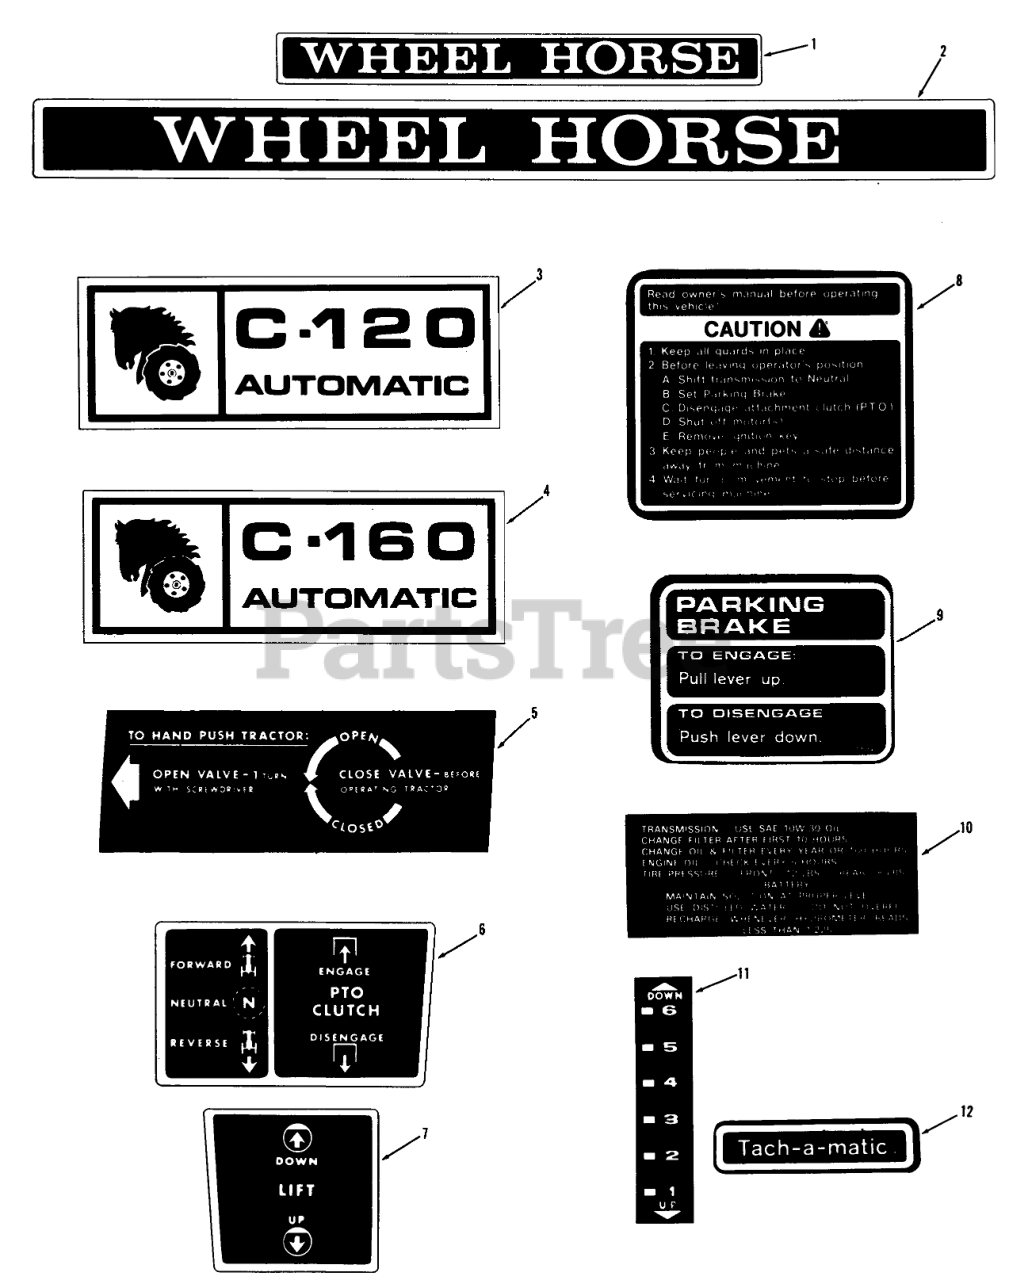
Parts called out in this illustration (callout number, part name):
1	DECAL-WHEEL HORSE
2	Decal
3	Decal
4	DECAL C 160
5	Lockwasher
6	DECAL PTO SPD. CONT
7	DECAL-HAND LIFT
8	Decal-Caution
9	Decal-Parking Brake
10	Decal-Maintenance
11	Decal
12	Decal-Tach-a-matic
